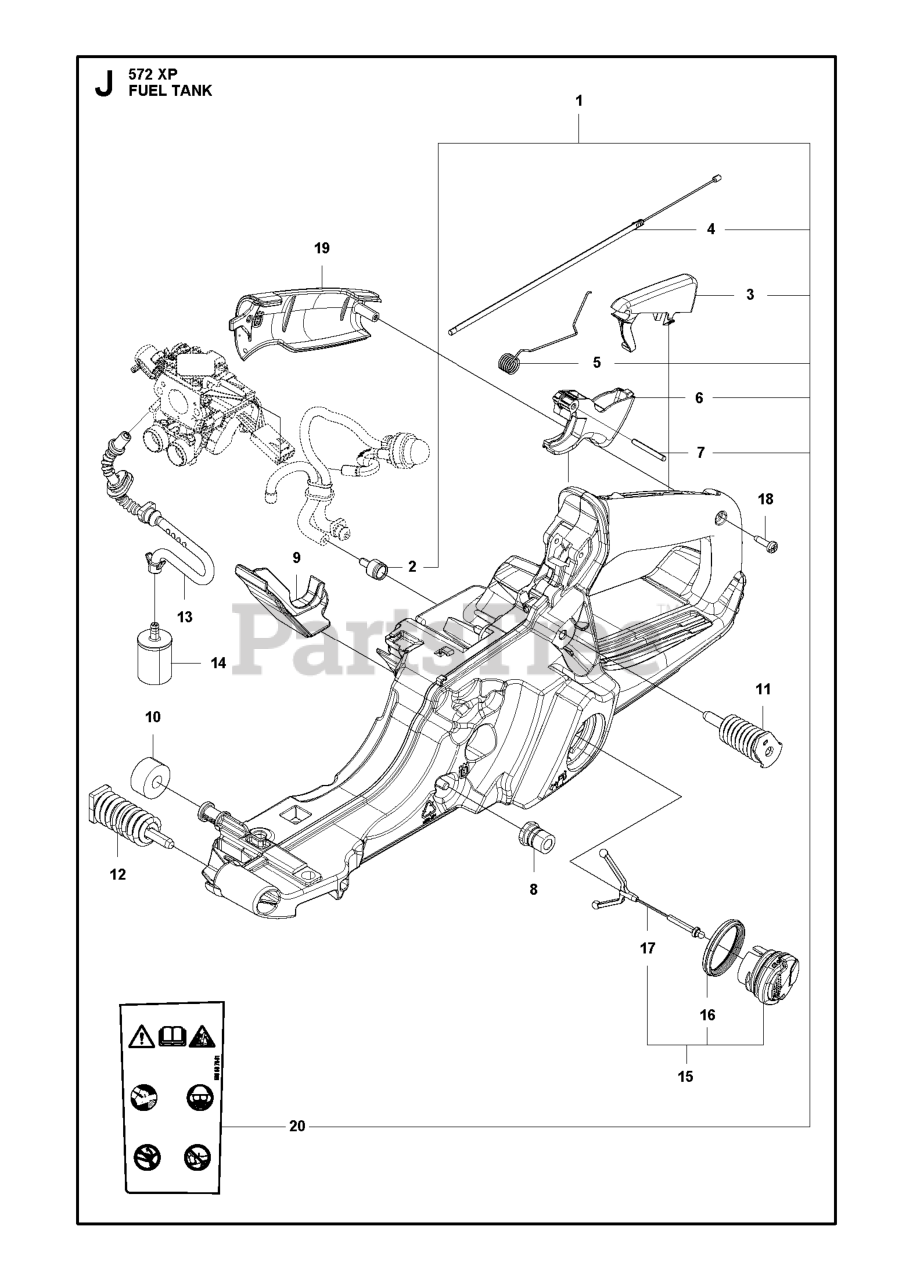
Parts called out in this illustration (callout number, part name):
1	FUEL TANK ASSY STANDARD SPARE
2	FUEL TANK VENT
3	THROTTLE LOCK
4	THROTTLE CABLE ASSY
6	THROTTLE TRIGGER CHAINSAW 70CC
8	LATERAL SUPPORT
9	WEAR PROTECTION FUEL TANK
10	DEFLECTION LIMITER
11	ANTIVIBRATION ELEMENT REAR
11	ANTIVIBRATION ELEMENT REAR HAR
12	ANTIVIBRATION ELEMENT FRONT
12	ANTIVIBRATION ELEMENT
13	FUEL HOSE
14	RP FUEL FILTER
15	TANK CAP ASSY
18	SCREW CITXPANT
19	COVER
19	HANDLE INSERT ASSY HEAT
20	DECAL SPARE PART H565/H572
